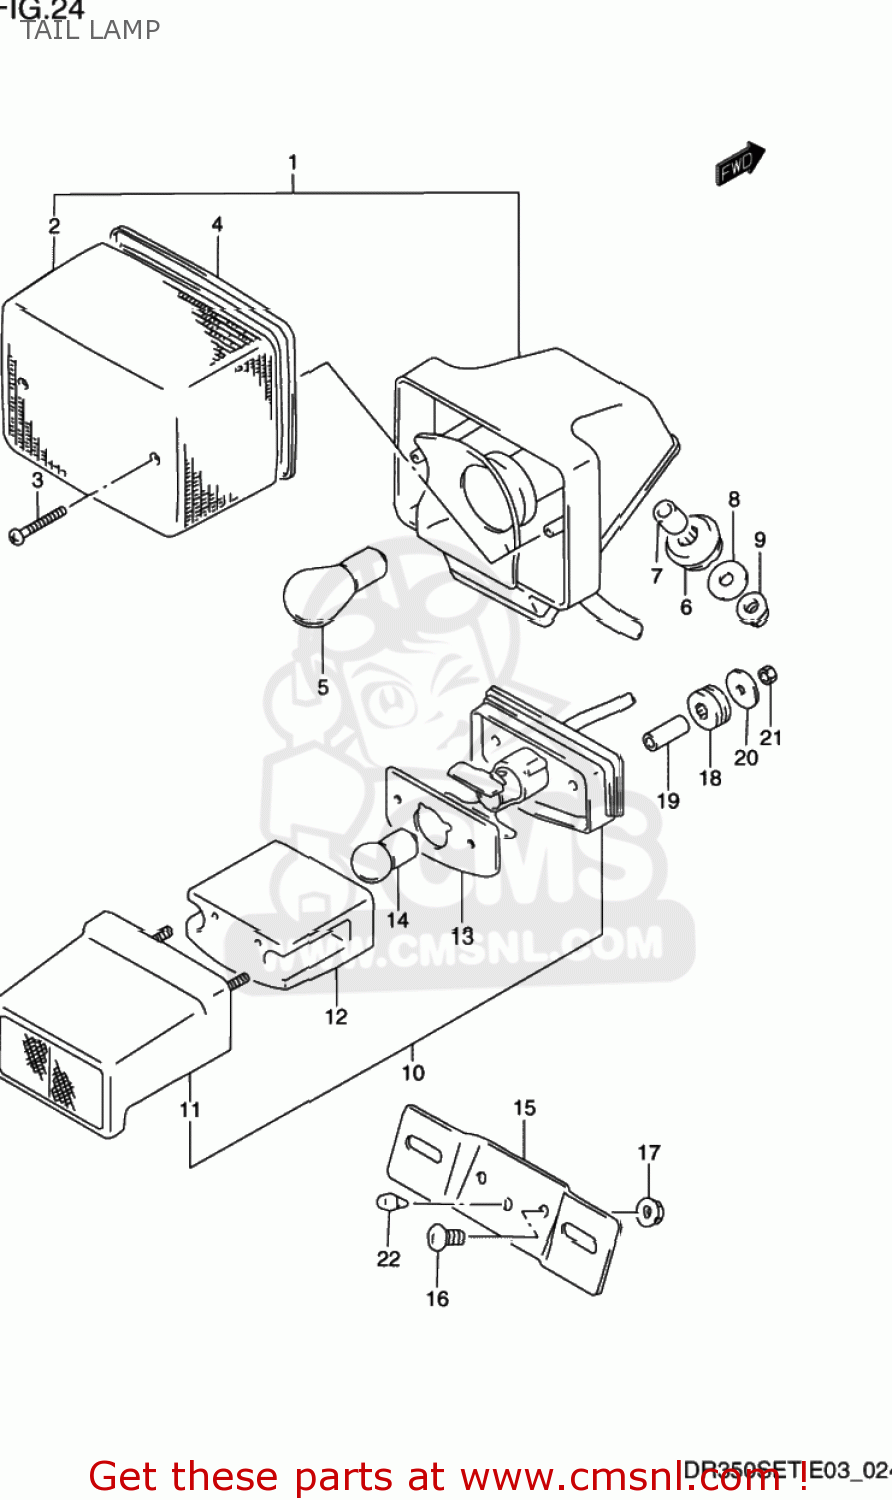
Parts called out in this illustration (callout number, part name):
1	LAMP ASSY,RR COMBINATION
2	LENS,TAIL LAMP
3	SCREW(4X45)
4	GASKET,LENS (NAS)
5	BULB(12V21/5W)
6	CUSHION
7	SPACER (6.1X9X9)
8	WASHER,COVER,FRONT
9	NUT
10	LAMP ASSY,LICENSE
11	REFLECTOR/COVER
12	LENS
13	GASKET,LICENSE LAMP (NAS)
14	BULB
15	BRACKET,LICENSE PLATE
16	SCREW
17	NUT
18	CUSHION
19	SPACER,LICENSE LAMP
20	WASHER(5.5X20X1.2)
21	NUT
22	CUSHION
